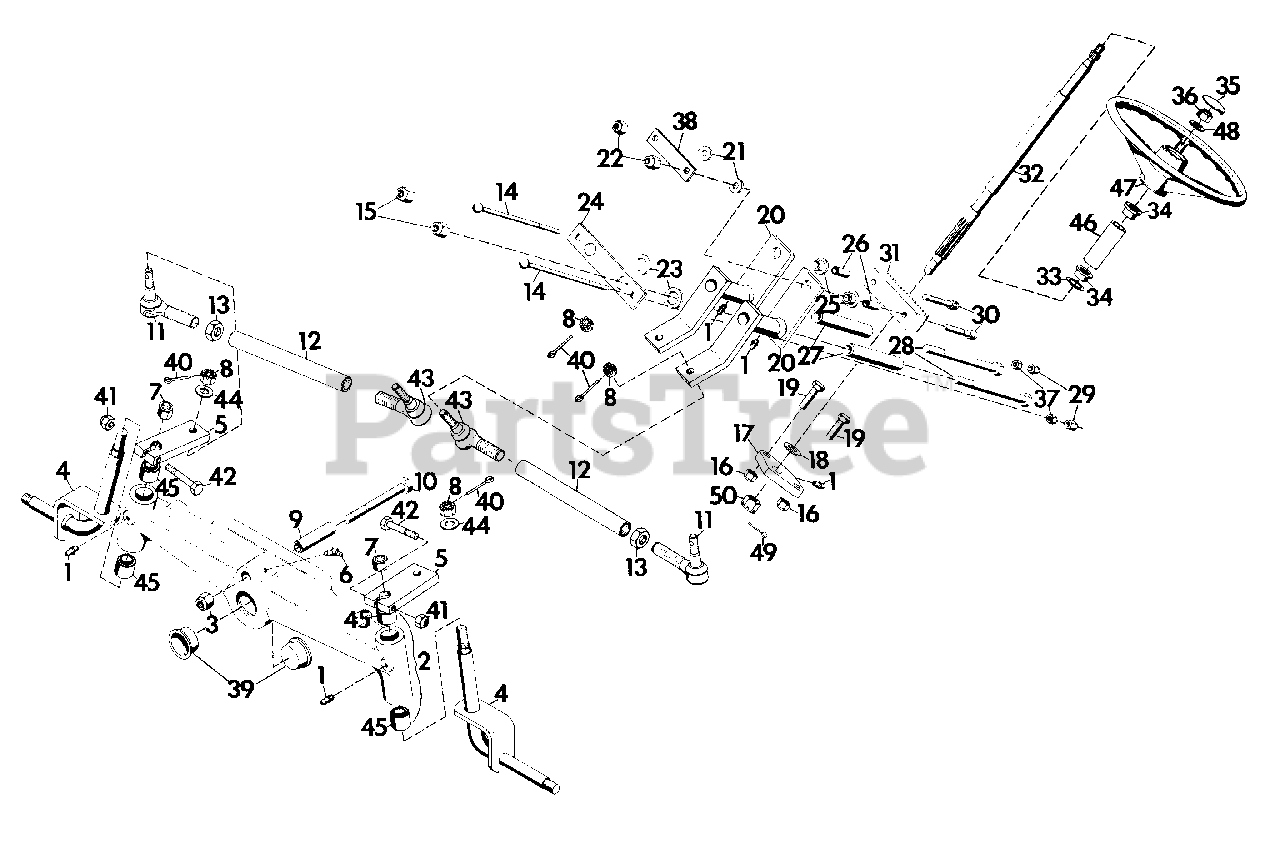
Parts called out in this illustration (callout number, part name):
1	FITTING, LUBE 1/4-28
2	ASSEMBLY, STEERING AXLE
3	NUT, LOCK 3/4-10
4	WELDMENT, KING PIN
5	ARM, TIE ROD AXLE
6	FITTING, LUBE 1/4-28 45 DEG. ELBOW
7	NUT, HEX 5/8-11
8	NUT, HEX SLOTTED 3/8-24
9	TUBE, AXLE PIVOT
10	BOLT, HEX 3/4-10X4.5
11	ASSEMBLY, ROD END R.H.
12	TUBE, TIE ROD
13	NUT, JAM 1/2-20
14	BOLT, 5/16-18X5.5 RD HD SQ NK
15	NUT, LOCK 1/2-13
16	NUT, LOCK 7/16-14
17	SUPPORT, STEERING SHAFT
18	RACE, THRUST
19	BOLT, HEX 7/16-14X1.5
20	WELDMENT, STEERING ARM
21	WASHER, FLAT .375X1.125X.065
22	NUT, LOCK 3/8-16
23	RACE, BEARING THRUST .752X1.240X.095
24	PLATE, ADJUSTMENT
25	BEARING, FLANGE(P/M BRONZE)
26	BUSHING .391X.622X.670
27	SLEEVE, PIVOT
28	BOLT, HEX 1/2-13X6.0
29	NUT, LOCK 5/16-18
30	SCREW, CAP 3/8-16X2.0 HEX SOCKET HD
31	GEAR, RACK
32	SHAFT, STEERING WHEEL
33	RING, RETAINING INT. TOOTH 1.000 SHAFT
34	BUSHING, NYLON .760X1.000X.600 FLANGE
35	CAP, STEERING WHEEL
36	NUT, JAM 5/8-11 HEX
37	NUT, HEX 5/16-18
38	STRAP, RACK AND PINION
39	CAP, FRONT AXLE
40	PIN, COTTER .09X.75
41	NUT, LOCK 5/16-24
42	BOLT, HEX 5/16-24X1.75
43	ASSEMBLY, ROD END L.H.
44	WASHER, FLAT .438X1.000X.083
45	BUSHING, .877X1.004X1.0
46	BUSHING, STEERING WHEEL
47	WHEEL, STEERING
48	WASHER, FLAT .656X1.312X.095
49	PIN, COTTER .09X.75
50	NUT, HEX 1/2-13 SLOTTED
